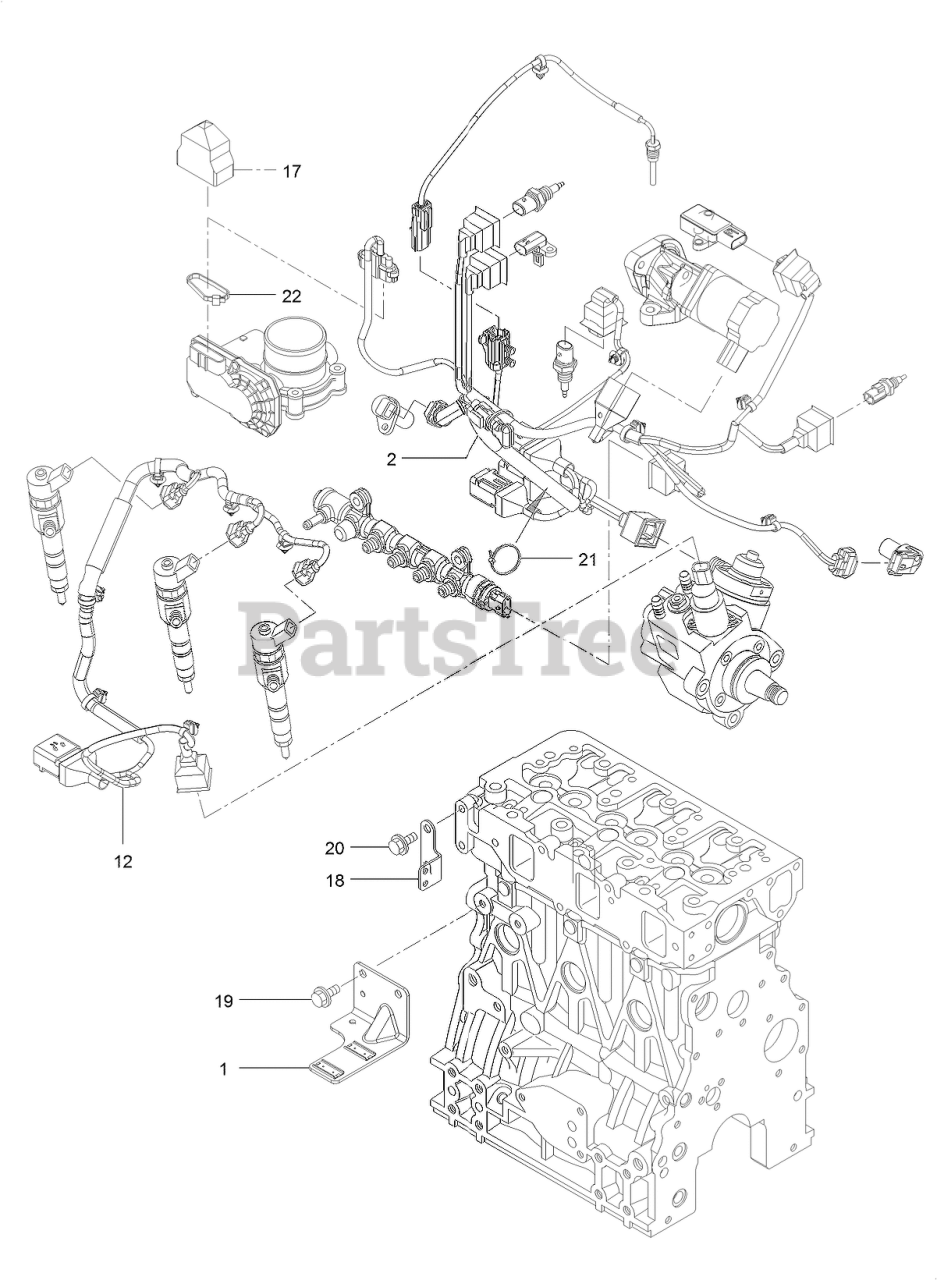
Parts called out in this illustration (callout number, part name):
1	BRACKET-CONNECTOR
2	HARNESS
12	HARNESS
17	Boot-Cap
18	Bracket-Harness
